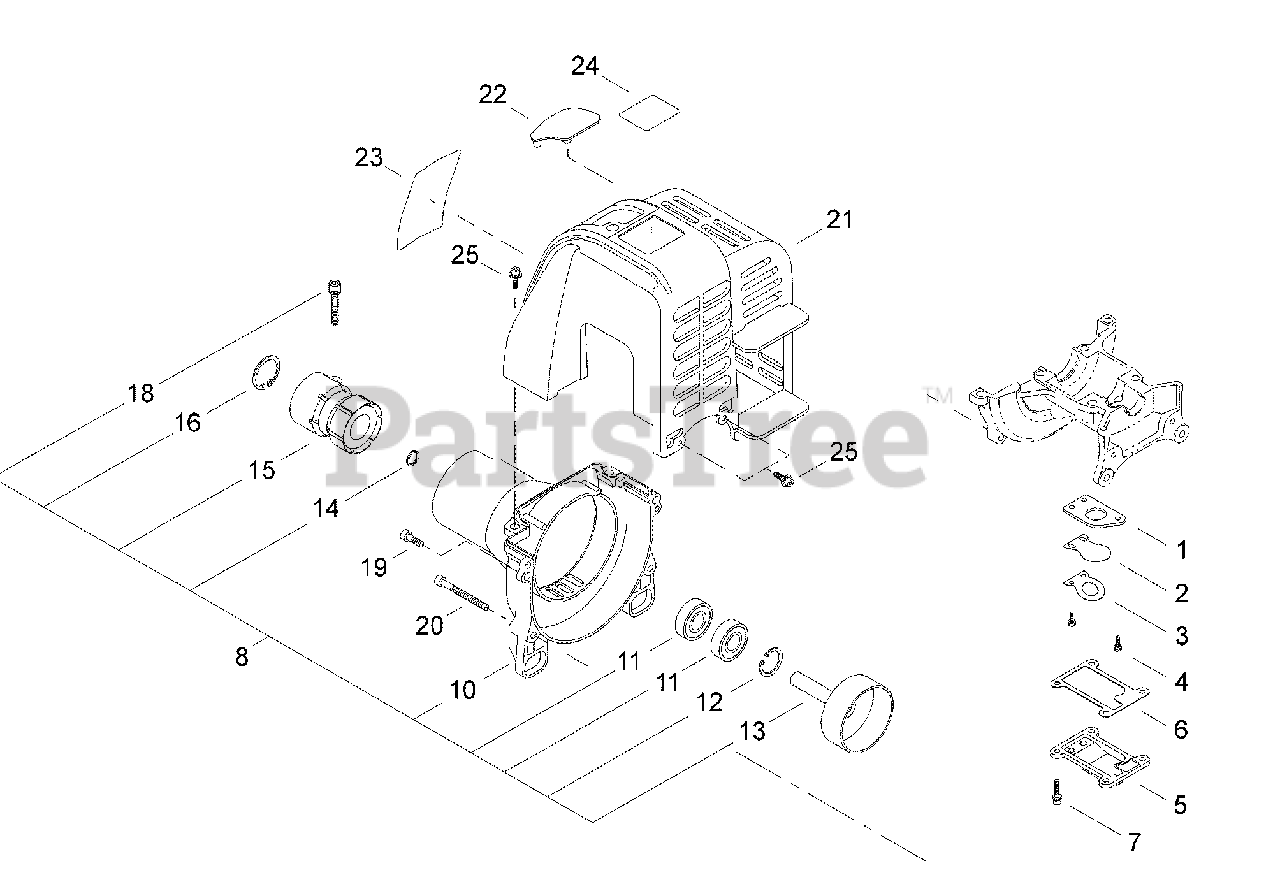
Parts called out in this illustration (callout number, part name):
1	PLATE, REED BACKING
2	VALVE, REED
3	STOP, REED VALVE
4	SCREW - 3X10
5	COVER, REED VALVE
6	GASKET, REED VALVE
7	SCREW - 4X12
8	FAN CASE ASSY
10	CASE, FAN
11	BEARING, BALL - 6000
12	RING, RETAINING - 26
13	DRUM, CLUTCH
14	RING, RETAINING
15	CUSHION
16	RING, RETAINING - 40
18	SCREW - 5X22
19	SCREW - 5X16
20	SCREW - 5X45
21	COVER, ENGINE
22	COVER, SPARK PLUG
23	LABEL - C4
24	LABEL - MODEL
25	SCREW - 4X16
